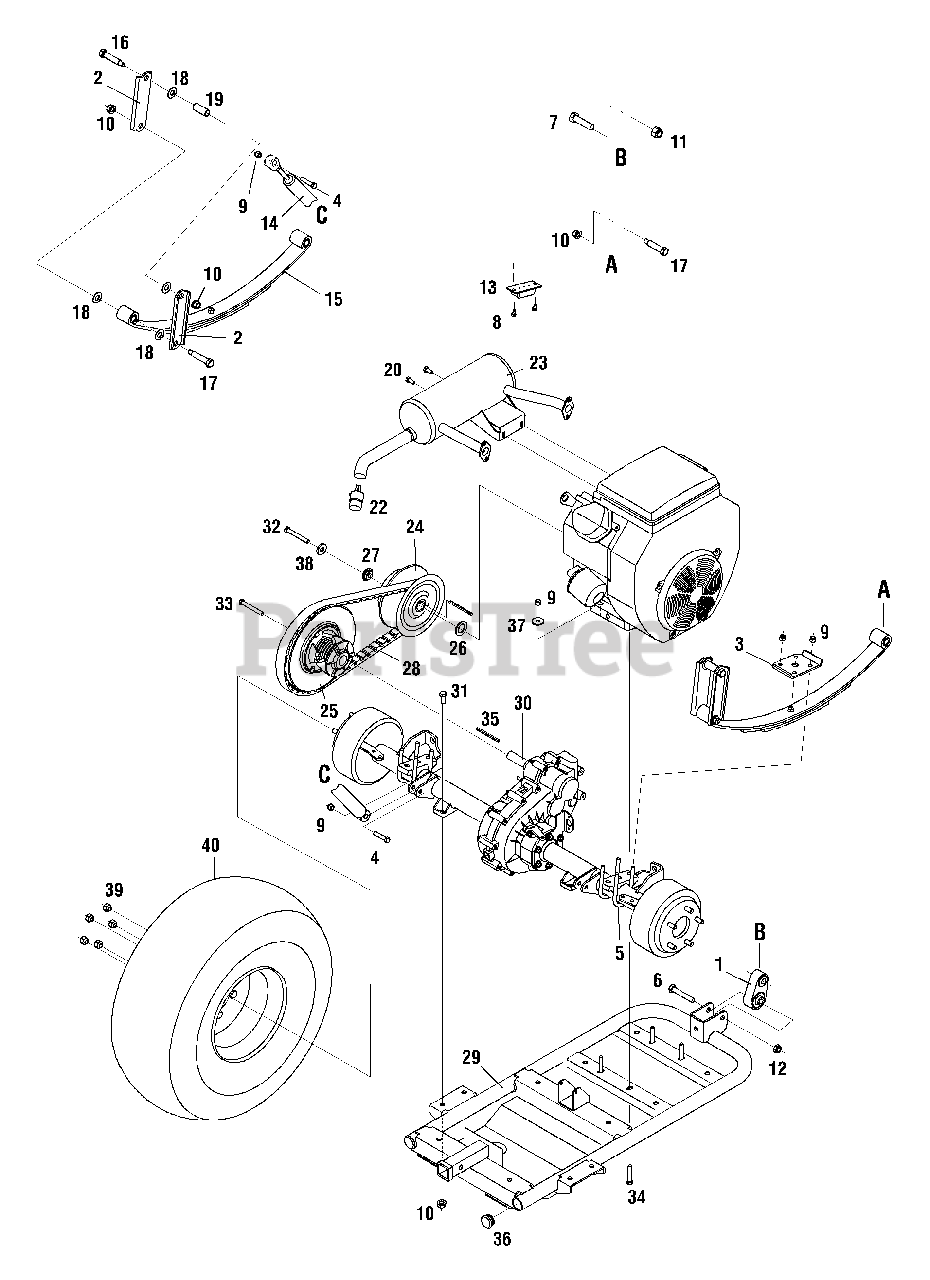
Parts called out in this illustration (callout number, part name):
1	Link Assembly
2	Plate, Shackle
3	Bracket, Spring Leaf
4	Hex Screw, 3/8-16 x 1.75
5	U-Bolt 3/8-16
6	Hex Screw, M12-1.75
7	Hex Screw, 5/8-11 x 2.5
8	Screw, Self Tapping 1/4-20
9	Locknut, Nylon, 3/8-16
10	Hexlock Nut
11	Hexlock Nut, Flange, 5/8 -11
12	Hexlock Nut, M12 x 1.75
13	Bumper, Suspension
14	Shock Absorber, 2.50 Stroke
15	Spring, Leaf 4 x 2
16	Shoulder Screw, .550 x 2.29
17	Shoulder Screw, .550 x 2.13
18	Bearing, .56 ID x 1.25 OD x .06
19	Bushing, .75 OD x .562 ID x 1.75 LG
20	Screw, M8 x 1.25:20
21	Valve, Oil Drain
22	Spark Arrestor
23	Muffler, Honda GXV
24	Clutch Assembly, Engine
25	Clutch Assembly, Transmission
26	Washer, Flat, 1.03 x 1.625 X .12
27	Spacer, .39 x 1.0
28	Belt, Cogged
29	Engine/Trans. Cradle
30	Transmission Ass'y, Diff-Lock
31	Hex Screw, 7/16-20 x 1.0
32	Hex Screw,3/8-24 x 3.00
33	Hex Screw, 1/2-20 x 2.25
34	Hex Screw,3/8-16 x 2.00
35	Key, Square 1875 x 3.25
36	Plug, Tube
37	Washer, Flat, .510 x 1.00 x .125
38	Washer, Flat, .531 ID x 1.25 X 1.00
39	Lug Nut, 7/16-14
40	Wheel Assembly, 25 x 12 x 9,Turf
